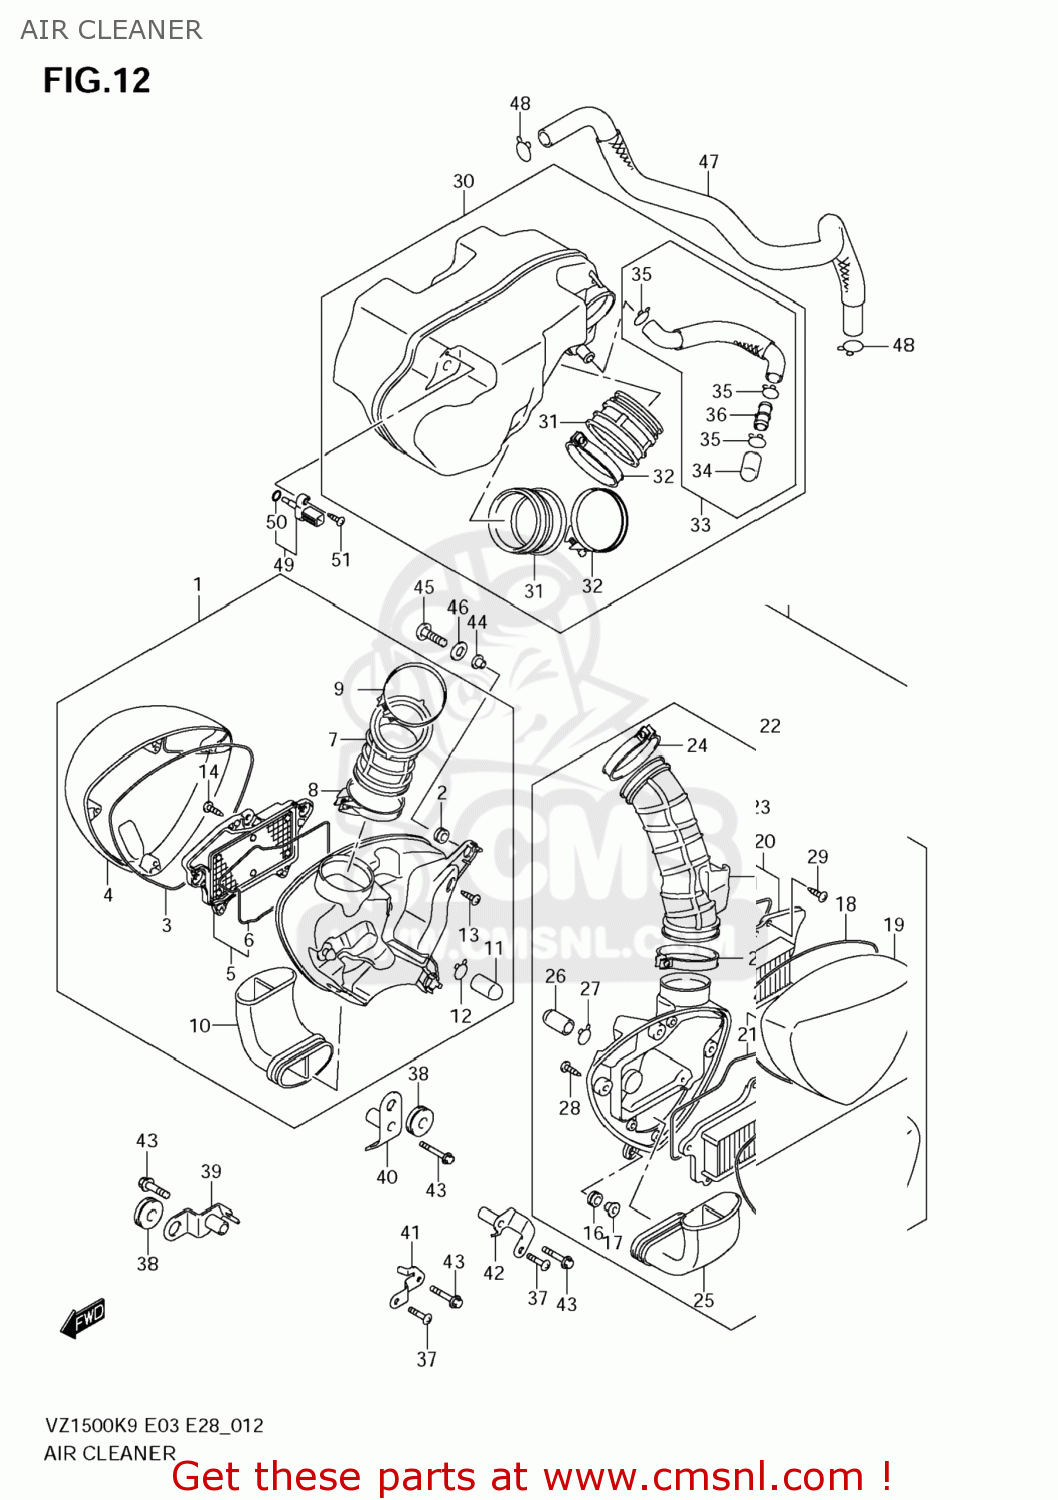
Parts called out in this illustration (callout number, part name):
1	CLEANER,AIR R
2	CUSHION
3	GASKET,CASE
4	CAP,AIR CLEANER
5	FILTER ASSY
6	GASKET (NAS)
7	TUBE,JOINT,R
8	CLAMP
9	CLAMP
10	TUBE,INLET
11	PLUG,DRAIN
12	CLIP
13	SCREW
14	SCREW
15	CLEANER COMP,A
16	CUSHION
17	COLLAR,CLEANER CASE
18	GASKET,CASE
19	CAP,AIR CLEANER
20	FILTER ASSY
21	GASKET (NAS)
22	TUBE,JOINT,L
23	CLAMP
24	CLAMP
25	TUBE,INLET
26	PLUG,DRAIN
27	CLIP
28	SCREW
29	SCREW
30	CHAMBER COMP,A
31	TUBE,OUTLET
32	CLAMP,INTAKE PIPE
33	TUBE,DRAIN
34	PLUG
35	CLIP
36	JOINT,2ND AIR CLEANER HOSE
37	BOLT(6X20)
38	CUSHION
39	BRACKET,AIR CLEANER,R NO.1
40	BRACKET,AIR CLEANER,L NO.1
41	BRACKET COMP,A
42	BRACKET,AIR CLEANER,L NO.3
43	BOLT(6X30)
44	SPACER,AIR CLEANER
45	BOLT(6X35)
46	WASHER(6.5X18X1.6)
47	TUBE,BREATHER
48	CLIP
49	SENSOR,AIR TEMP
50	O RING
51	SCREW
